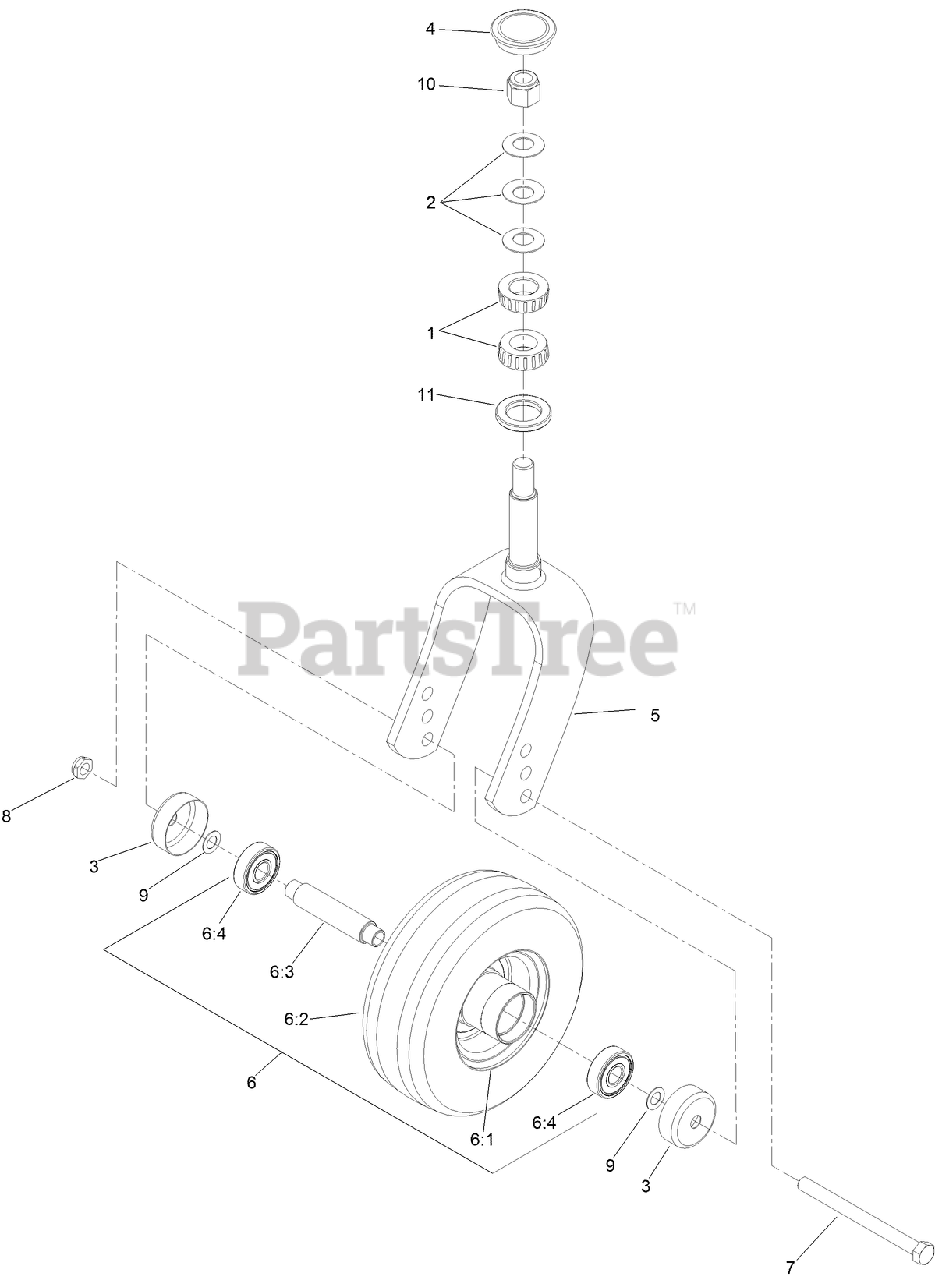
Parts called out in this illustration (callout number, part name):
1	BEARING-ROLLER, TAPERED
2	WASHER-BELLVILLE
3	GUARD-SEAL
4	CAP-GREASE
5	FORK-CASTER
6	WHEEL AND TIRE ASM
6:1	WHEEL
6:3	AXLE-CASTER
6:4	BEARING
7	SCREW-HH
8	NUT-HEX
9	WASHER-PLAIN
10	NUT-LOCK, NI
11	SEAL-GREASE
